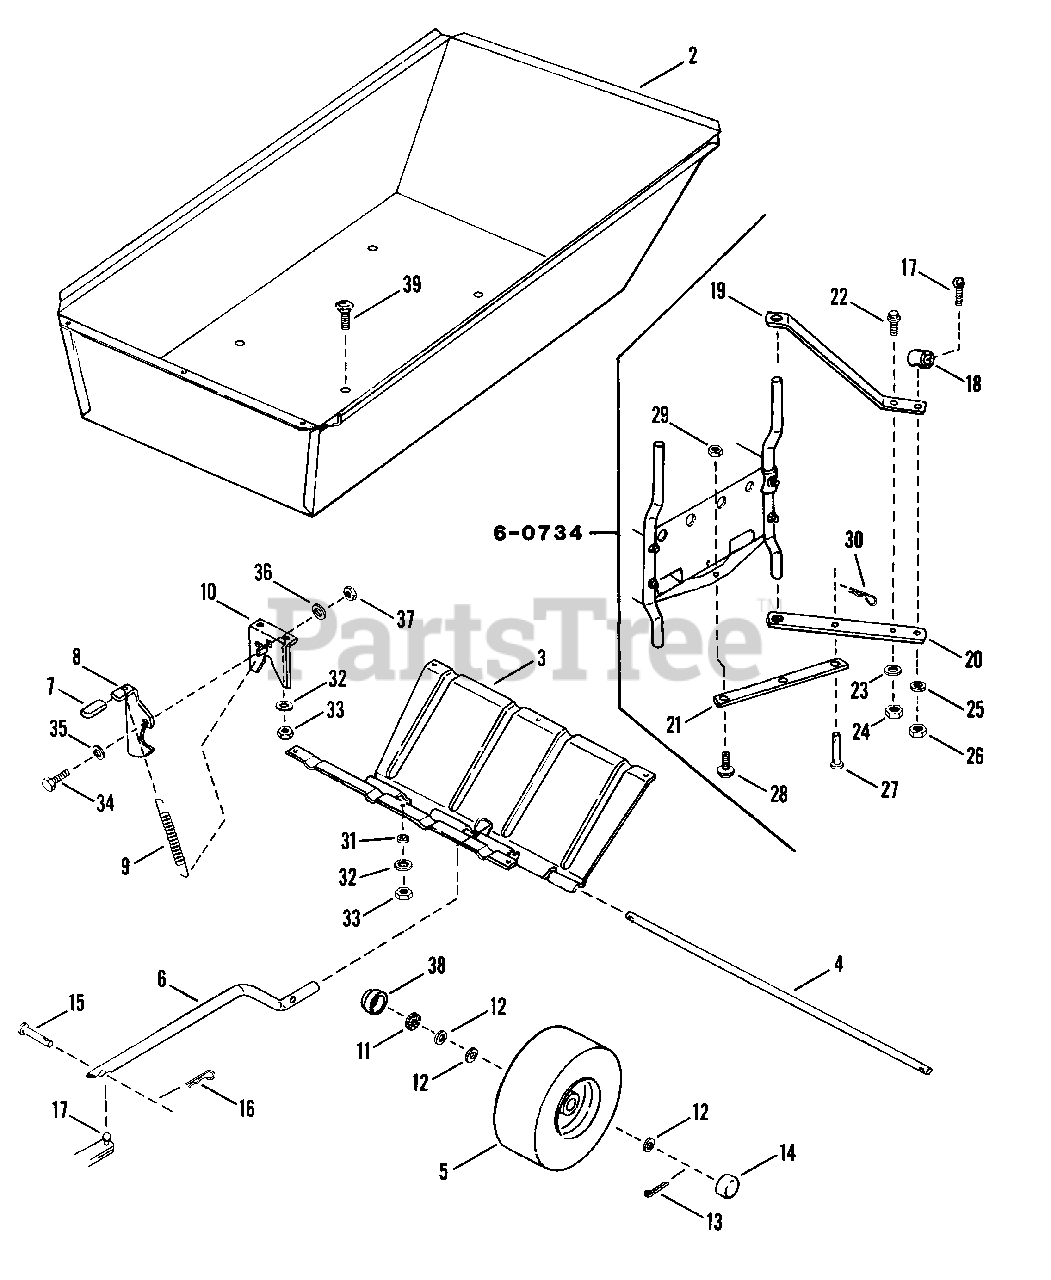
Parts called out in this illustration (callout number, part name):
2	BODY, Wagon Cart
3	SUPPORT, Axle
4	AXLE
5	ASSEMBLY, Tire & Rim
6	TONGUE
7	GRIP, Latch
9	SPRING, Latch
10	YOKE
11	WASHER, Felt
12	WASHER
13	COTTER-PIN, 5/32x1"
14	COVER, Dust
15	PIN, 3/8 Clevis
16	PIN, Hair
17	BALL, Hitch
18	COLLAR, Hitch
19	BAR, Upper Draw
20	BRACE, Draw Bar
21	BAR, Lower Draw
22	CAPSCREW, 3/8-24x1" Hex Head
23	LOCKWASHER, 3/8 Split
24	NUT, 3/8-24 Hex
25	LOCKWASHER, 7/16 Split
26	NUT, 7/16-20 Hex
27	PIN, Hitch Clevis
28	CAPSCREW, 1/2-20x1" Hex Head
29	LOCKNUT, 1/2-20 Hex
30	PIN, Hair
31	RETAINER, 1/4 Bolt
32	LOCKWASHER, 1/4 Internal Tooth
33	NUT, 1/4-20 Hex
34	BOLT, 5/16-18 Shoulder
35	WASHER, Spring
36	LOCKWASHER, 5/16 Split
37	NUT, 5/16-18 Hex
38	DUST-CAP
39	CARRIAGE BOLT, 1/4-20x3/4"
60734	ASSEMBLY, Hitch
